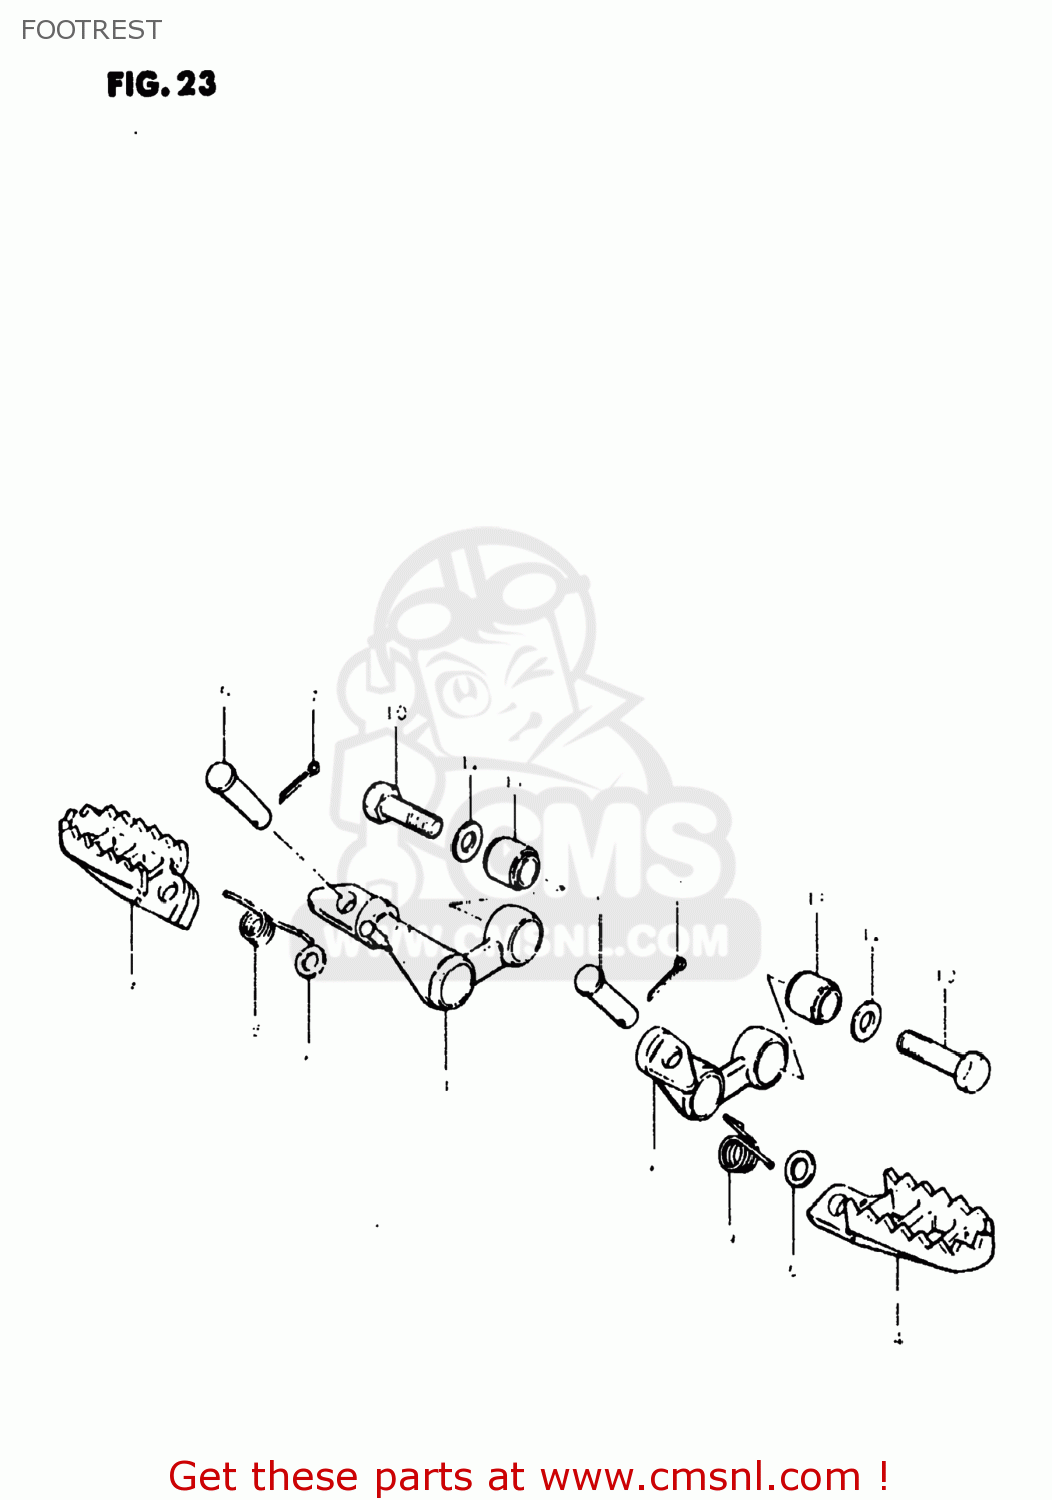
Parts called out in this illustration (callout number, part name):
1	BAR,FRONT FOOTREST
2	BAR,FRONT FOOTREST,LEFT
3	FOOTREST,RIGHT
4	FOOTREST
5	PIN
6	WASHER
7	PIN 30X20
8	SPRING
9	SPRING
10	BOLT
11	BUSH
12	WASHER (10.1X21X2.3)
